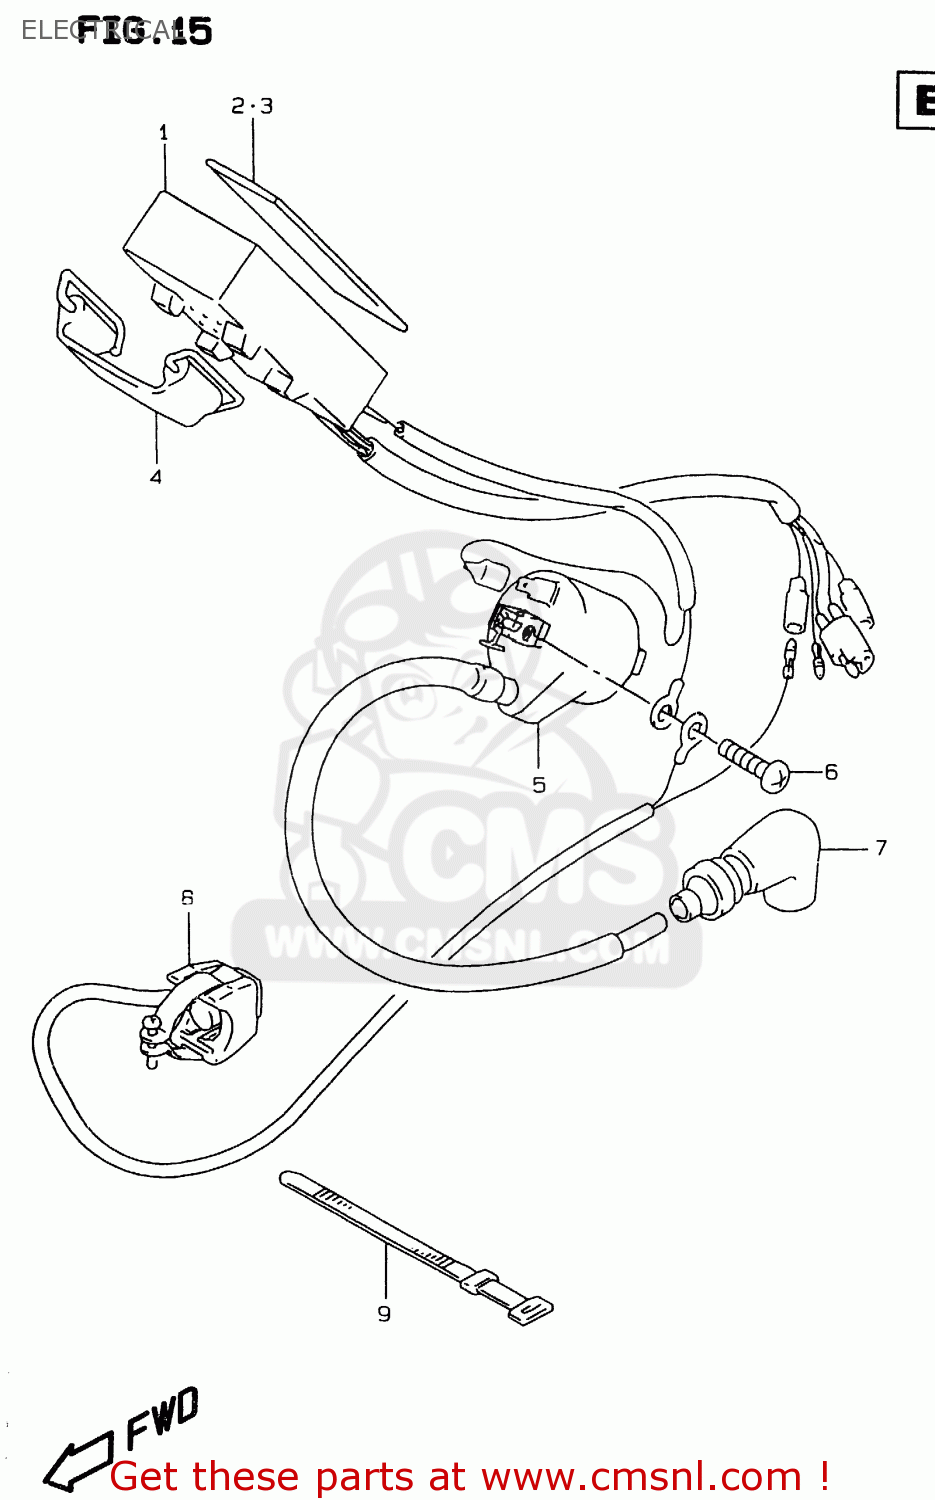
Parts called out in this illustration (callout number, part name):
1	CDI UNIT
2	PROTECTOR(170X95X3.0)
3	PROTECTOR(170X95X3.0)
4	BAND(L:65)
5	COIL ASSY, IGNITION
6	SCREW, 6X20
7	CAP,SPARK PLUG
8	SWITCH ASSY,ENGINE STOP
9	CLAMP(L:120)
